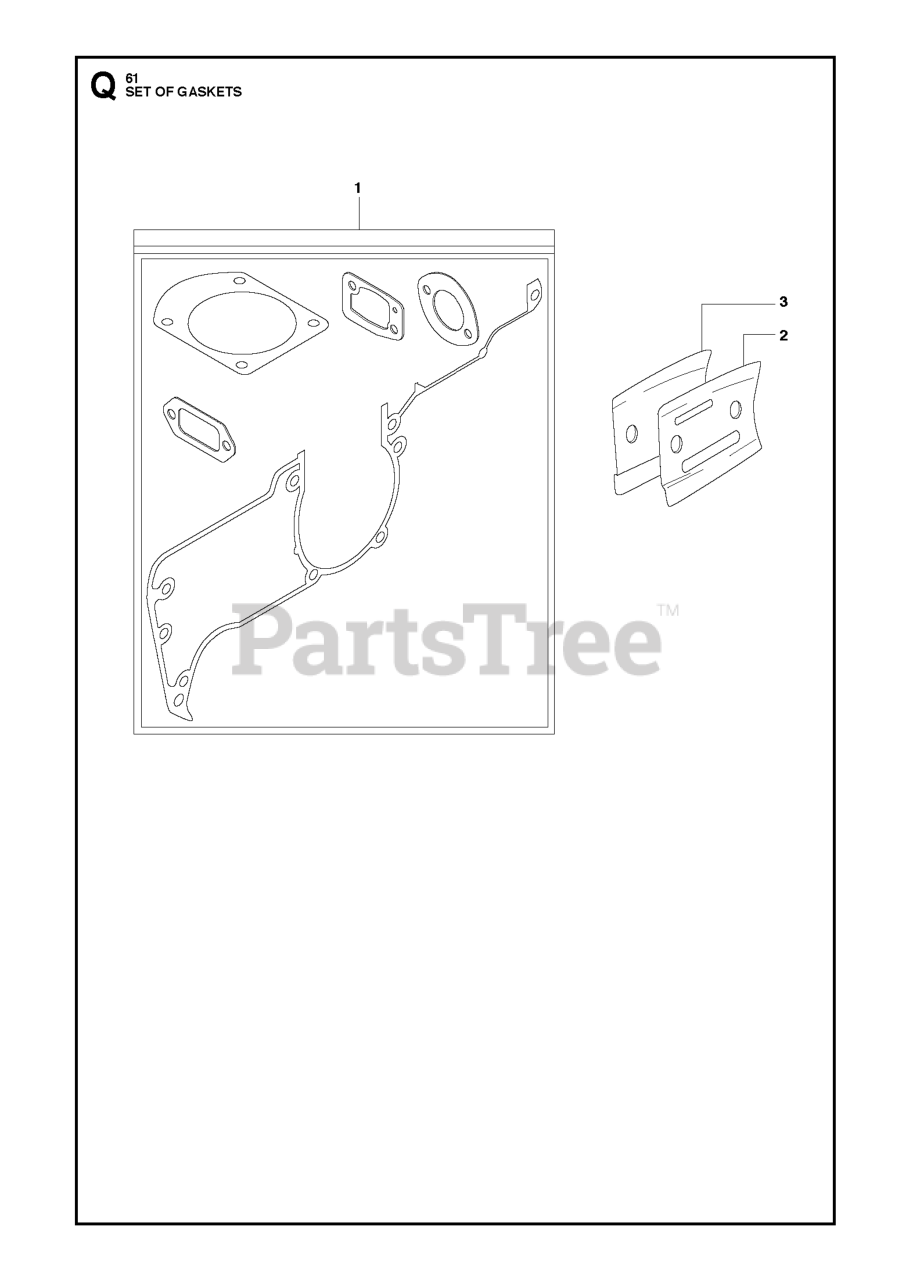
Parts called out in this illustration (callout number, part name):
1	GASKET SET NLA
2	GUIDE PLATE
3	GUIDE PLATE
